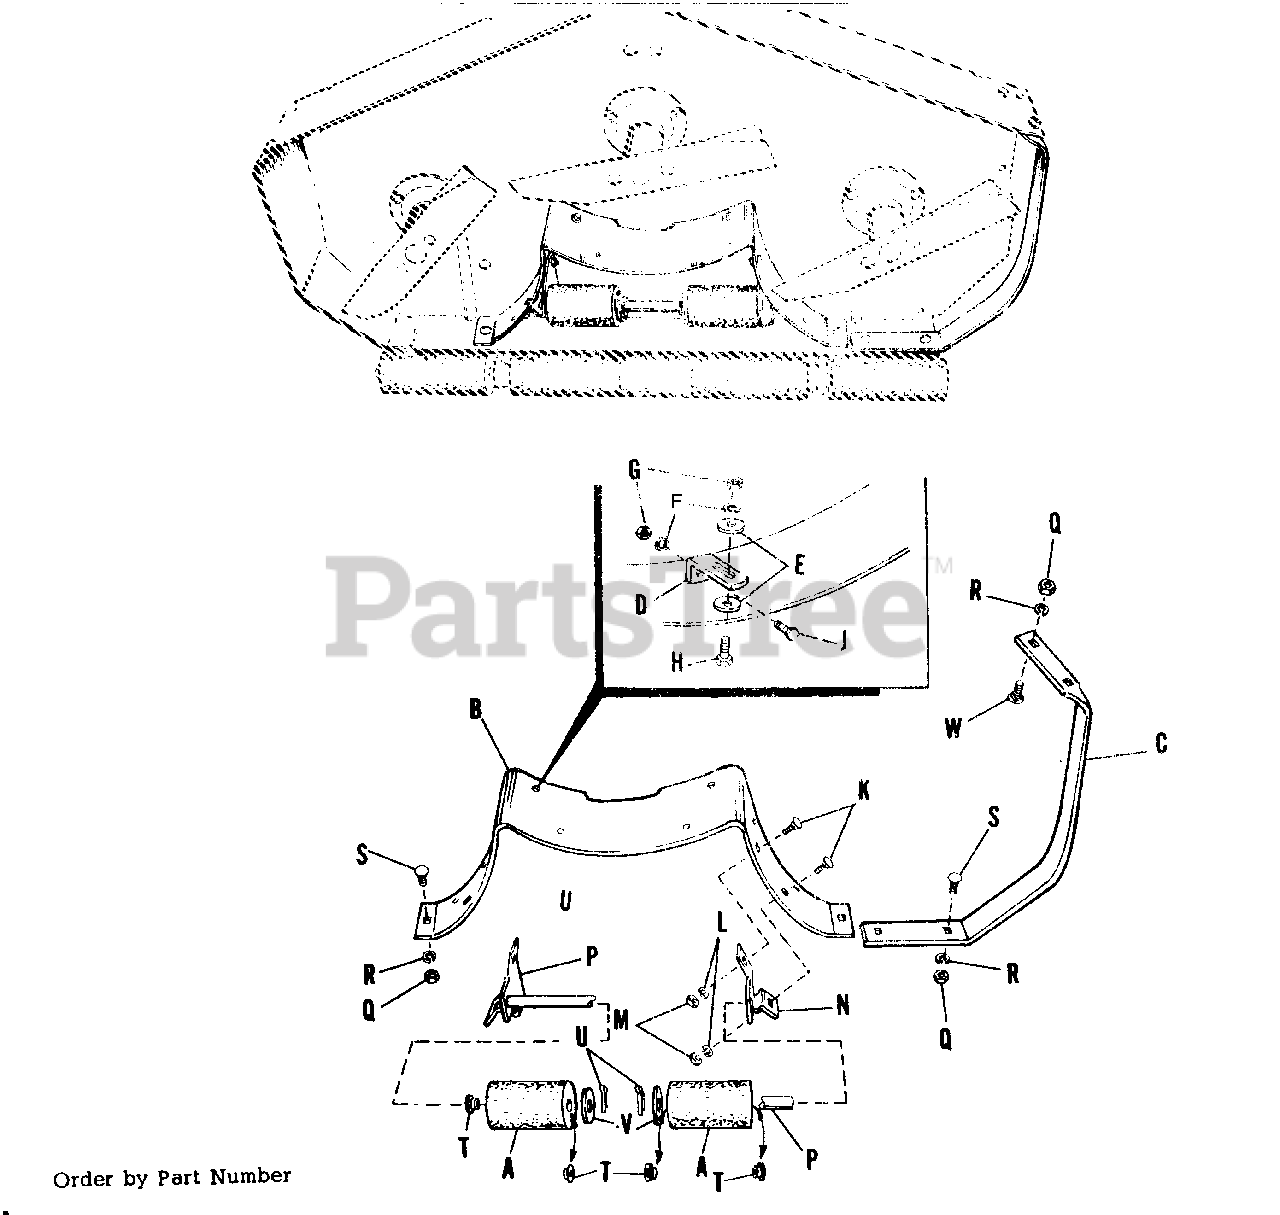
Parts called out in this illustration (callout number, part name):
A	ROLLER, .652 ID, 2.50 OD, 4.10 LG
C	Guard Assembly, Housing
D	Clip Baffle
E	Washer, Plain, 1/4"
F	Washer, Lock, 1/4"
G	Nut, Hex, Full, 1/4"-20 NC
H	Capscrew, Hex, 1/4"-20 x 5/8" lg.
J	Screw, Recessed Hex, Self-Tapping 1/4"-20 NC x 7/8" lg.
K	Bolt, Carriage, 5/16"-18 NC x 3/4" lg.
L	Washer, Lock, 5/16"
M	Nut, Hex, Full, 5/16"-18 NC
N	Bracket, Roller, Lower, L.H.
P	Bracket & Shaft Assembly
Q	Nut, Hex, Full, 3/8"-16 NC
R	Washer, Lock, 3/8"
S	Bolt, Carriage, 3/8"-16 NC x 3/4" lg.
U	Pin, Cotter, 3/16" x 1" lg.
W	Bolt, Carriage, 3/8"-16 NC x 1" lg.
